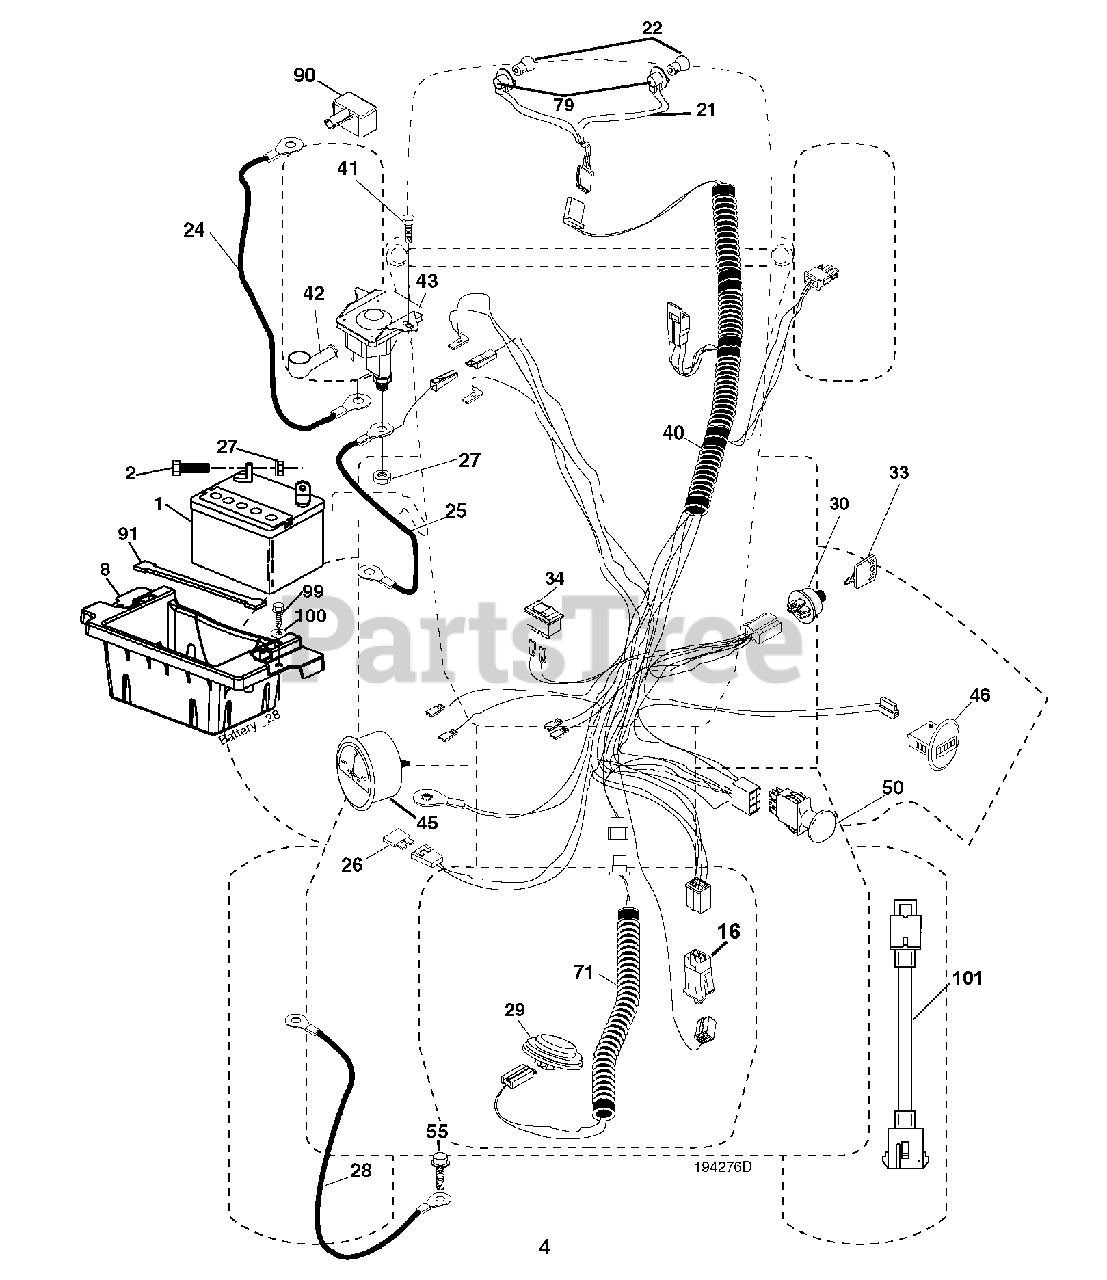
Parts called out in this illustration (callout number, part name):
1	BATTERY 12V .35 AMP
8	BOX.BATTERY.MOUNT.FRONT.LT
16	SWITCH INTERLOOK PUSH-IN
21	HARNESS.W/LIGHT SOCKET
22	LIGHTBULB
24	CABLE.BATT.POS.WIRE.TG.DA SOL
25	CABLE.START.RED.17.5".
26	FUSE 20AMP
27	NUT
28	CABLE GROUND 6 GA 21" 90T BLK
29	SWITCH.SEAT.DELTA.OPC.
30	SWITCH.IGN.DELTA.W.LGH.ROS
33	KEY MLD GEN DELTA
34	SWITCH LT
40	HARNESS IGN. DASH
41	SCREW
42	TERMINAL COVER
43	SOLENOID.W/BRASS.PLUNG
46	HOURMETER SNAP-IN
50	PTO SWITCH
55	SCREW 5/16"
71	HARNESS-CHASSIS SUB
79	BULB HOLDER ASM.
90	COVER.TERMINAL.BATTERY
91	STRAP, BATTERY MOUNT
99	SCREW HEXWSHR 1/4-20X3/4
101	PIGTAIL.MATNLK.NEW.HAR
